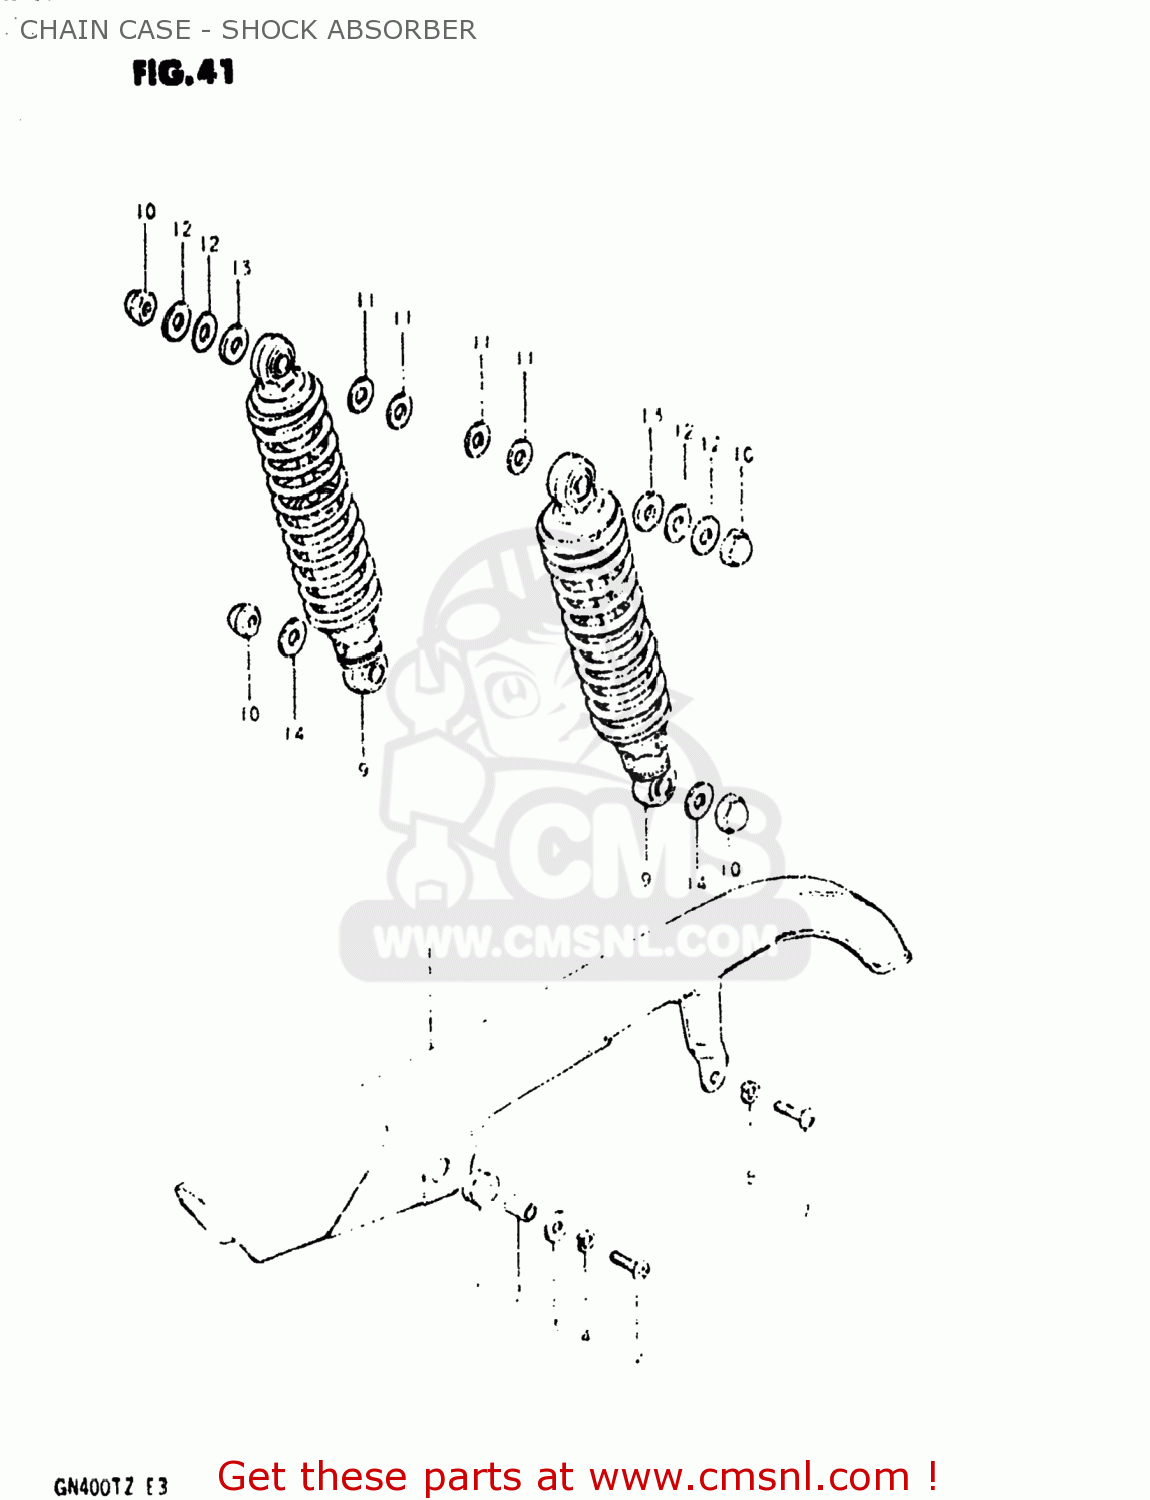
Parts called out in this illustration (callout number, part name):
1	CASE,CHAIN
2	SCREW
3	WASHER (6.5X20X1.2)
4	LOCK WASHER
5	SPACER (7X9X7)
6	CUSHION
7	SCREW
8	LOCK WASHER
9	ABSORBER ASSEMBLY,REAR SHOCK
10	NUT, LOWER LH
11	WASHER
12	WASHER
13	WASHER(10.5X24X3.2)
14	WASHER
